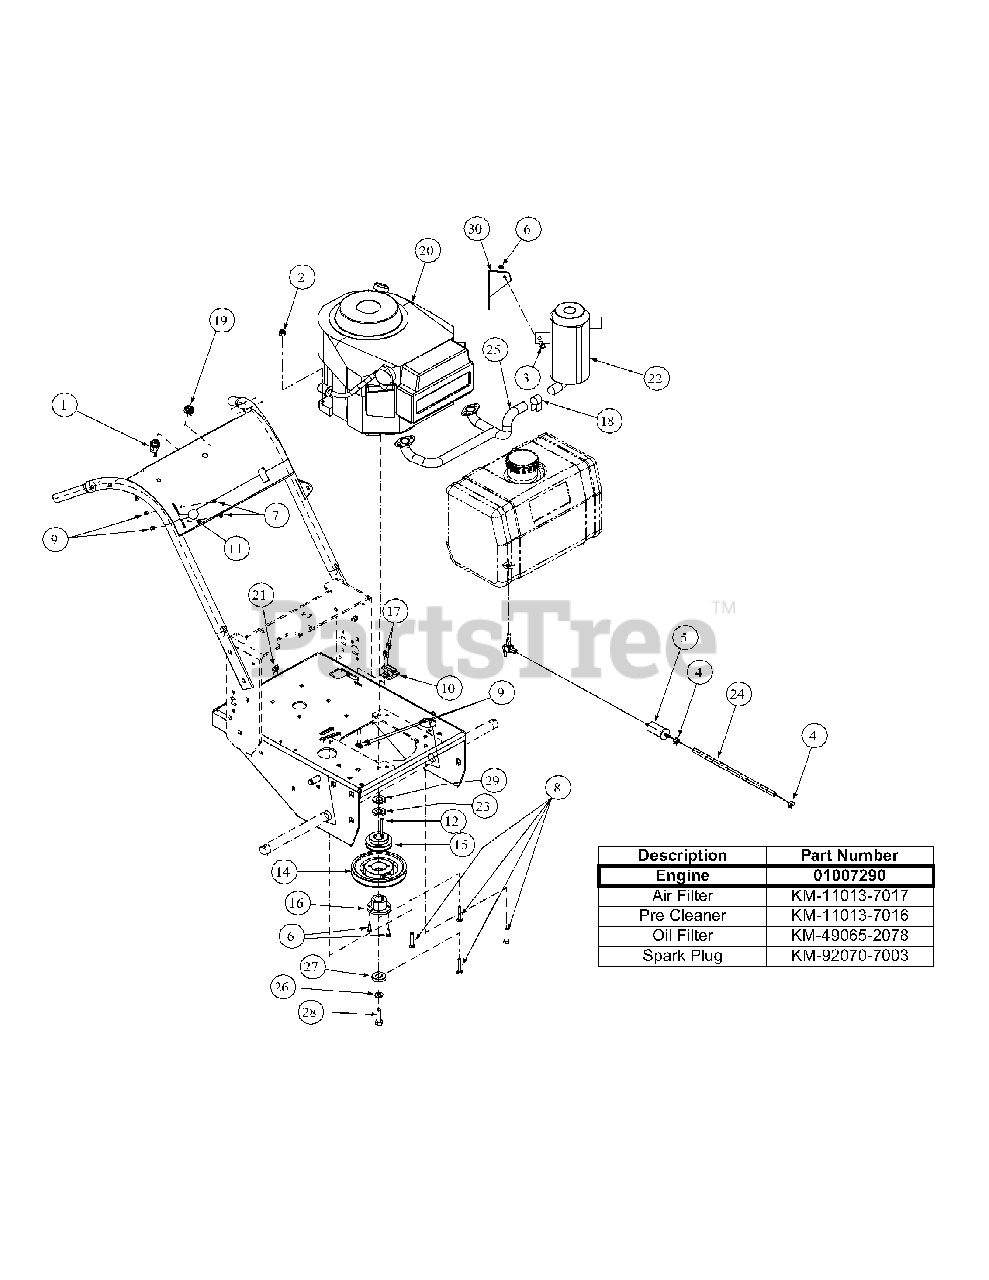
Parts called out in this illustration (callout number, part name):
1	Single Ignition ON/OFF Switch
2	Lock Nut, Nylon Insert, 5/16-18
3	Hex Cap Screw, 5/16-18 x 3/4
4	Clamp
5	Kohler Fuel Filter
6	Lock Nut, 5/16-18
7	Screw, Hex Washer, 10-32 x 1/2
8	HHCS, 5/16-18 x 2
9	Lock Nut, Nylon Insert, 10-32
10	Delta Switch
11	Control Throttle w/Detent, 39.2
12	Key Stick, 1/4 x 1/4 x 2-3/4
14	Deck Pulley
15	Traction Pulley
17	Machine Screw, 10-32 x 5/8
18	Muffler Clamp Assembly
19	Nut w/cap, 5/8-32 Ignition
20	13 Hp Kawasaki Engine
21	Support Clamp, 3/8 OD
23	Flat Washer
24	12" Fuel Hose
25	Kawasaki Manifold
26	Lock Washer, 7/16
27	Clutch Washer
28	Hex Cap Screw, M10 x 1.5, 30mm, GR10.9
29	Spacer, Engine Pulley
30	Muffler Bracket
